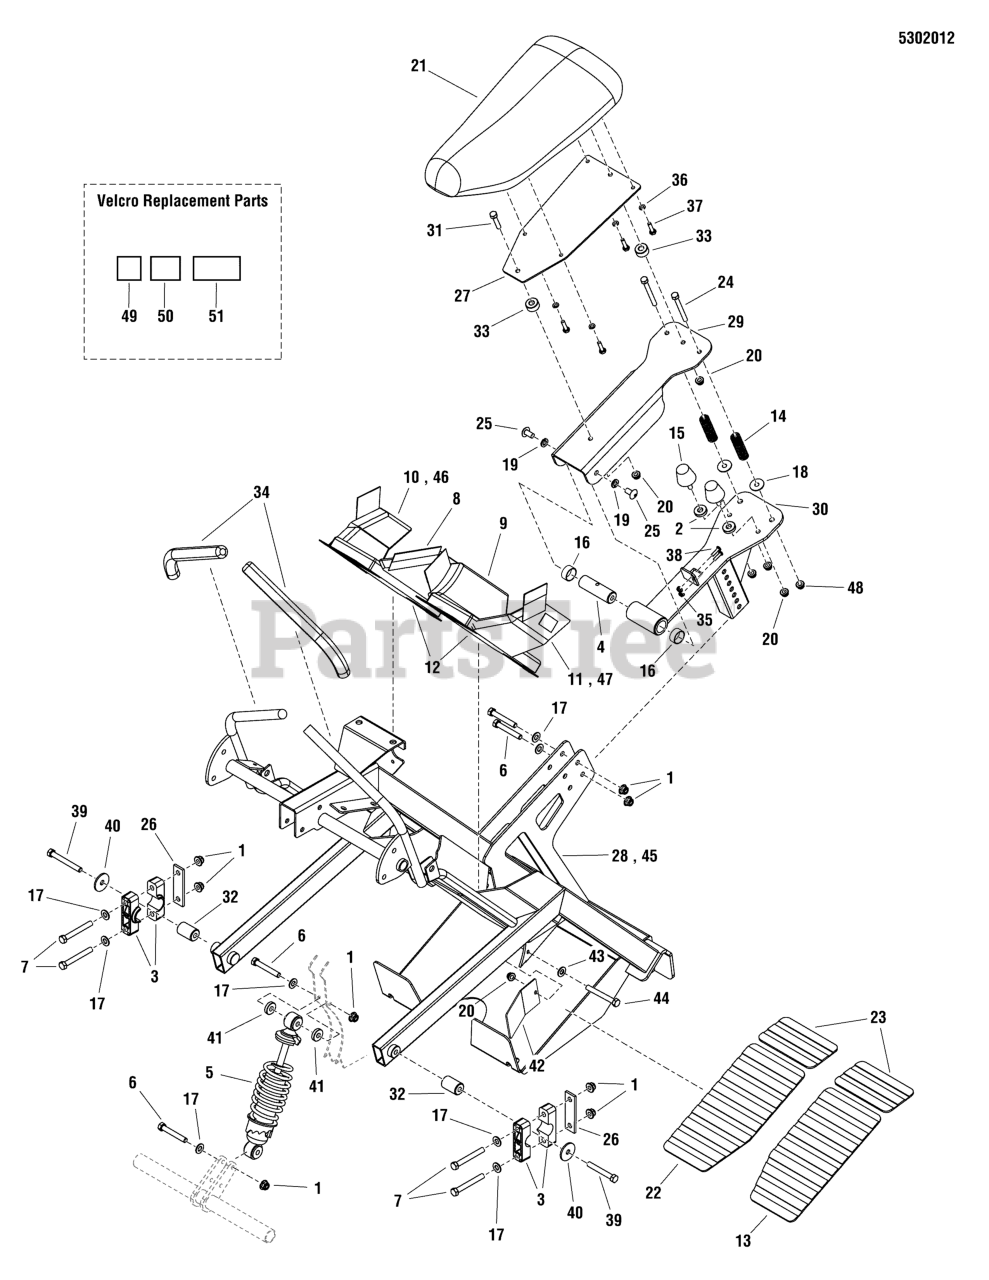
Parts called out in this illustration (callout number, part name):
1	NUT, 3/8-16 HEX NYLOCK FLANGE
2	SPACER, .39 X 1.00 X .25
3	PIVOT BLOCK, PLASTIC
4	SPACER, 1.00 X 3.25 THRD BOTH ENDS
5	SHOCK ABSORBER
6	BOLT, 3/8-16 X 2-1/2" GD5 CZ
7	BOLT, 3/8-16 X 3" GD5 CZ
8	KNEE PAD, INNER RH, EVOLUTION 36"/48"
9	KNEE PAD, INNER LH, EVOLUTION 36"/48"
10	KNEE PAD, OUTER RH, EVOLUTION 36"
11	KNEE PAD, OUTER LH, EVOLUTION 36"
12	KNEE PAD, CENTER, EVOLUTION 36"/48"
13	SAFETY WALK, EVOLUTION 36"
14	STAINLESS STEEL COMP. SPRING
15	BUMPER, RUBBER 5/16-18
16	BUSHING, 1.00 X 1.13 X 1.38, PLASTIC
17	WASHER, 3/8 SAE
18	WASHER, 5/16" SAE
19	WASHER, 3/8 SPLIT LOCK
20	NUT, 5/16-18 HEX NYLOCK FLANGE
21	SEAT, EVOLUTION
22	SAFETY WALK, 6.00 X 11.25
23	SAFETY WALK, 3.5 X 6.00
24	BOLT, 5/16-18 X 3-1/4 GD5
25	BOLT, 3/8-16 X 3/4,ALLEN BUTTON
26	PLATE, PIVOT BLOCK SUPPORT - BLK
27	PLATE, SEAT RAIL ADAPTER - RED
28	WELD, OPERATOR COMPARTMENT, 36
29	PLATE, SEAT MOUNT, TOP - RED
30	WELD, SEAT MOUNT - RED
31	BOLT, 5/16-18 X 1-3/4, CARRIAGE
32	SPACER, .515 X 1.00 X 1.22, YZ
33	SPACER, .39 X 1.00 X .50
34	FOAM, GRIP, 3/4" ID X 12" LG X .187 BLK
35	NUT, #10-24 HEX NYLON LOCK
36	WASHER, 1/4 LOCK
37	BOLT, 1/4-20 X 1" GD5 CZ
38	SCREW, #10-24 X 3/4 ROUND PHILLIPS
39	BOLT, 1/2-20 X 2-1/4 GD5 CZ
40	WASHER, 1/2 USS
41	SPACER, .390 X 1.00 X .190
42	GUARD, FOOT, EVO 36-48 - RED
43	WASHER, 5/16" SAE
44	BOLT, 5/16-18 X 1 GD5 YZ
45	WELD, OPERATOR COMPARTMENT, 48 - RED
46	KNEE PAD, OUTER RH, EVOLUTION 48/52
47	KNEE PAD, OUTER LH, EVOLUTION 48/52
48	ACORN NUT, 5/16-18 S/S
49	VELCRO, 2" X 2", HOOK MATERIAL
50	VELCRO, 2" X 2-1/2", HOOK MATERIAL
51	VELCRO, 2" X 4", HOOK MATERIAL
